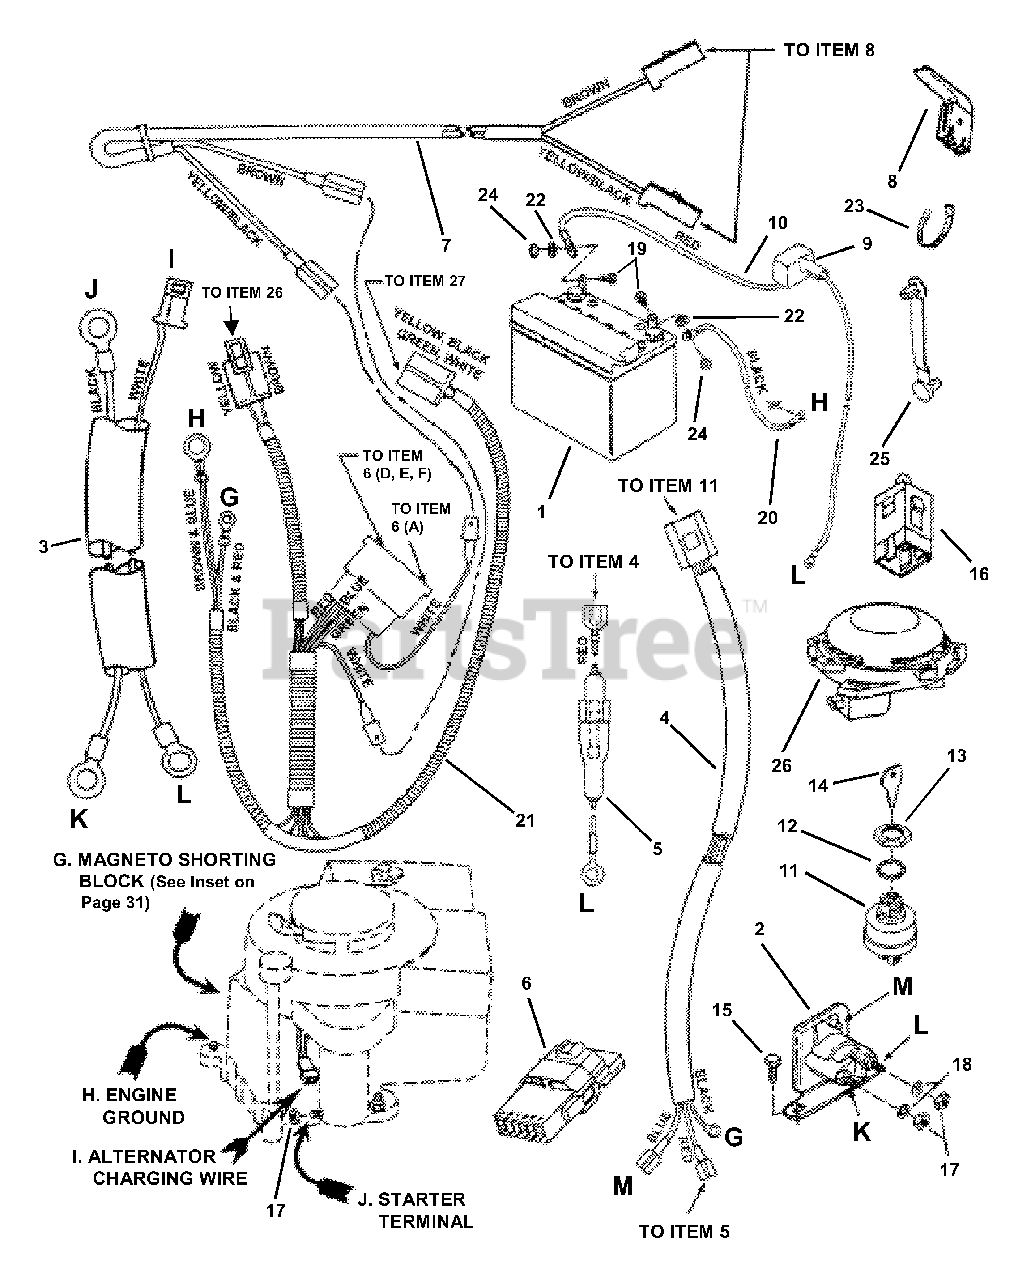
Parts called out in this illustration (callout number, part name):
1	KIT, 12Volt Dry Charge Battery
2	SOLENOID
3	HARNESS, Starter Wiring (Briggs Engines)
4	HARNESS, Ignition Wiring (Briggs Engines)
5	HOLDER, Fuse
6	INTERLOCK Module (Briggs)
7	HARNESS (Deck Interlock Wiring)
8	SWITCH, Deck Interlock (NO)
9	COVER, Battery Cable
10	CABLE, Positive (17" Long, Red)
11	SWITCH, Ignition
12	WASHER, 5/8 Internal Tooth Lock
13	NUT, 5/8-32 Hex
14	KEY, Switch
15	SCREW, 1/4-20 x 1/2" Hex Washer Self-Tap
16	SWITCH, Operator Presence Control (OPC) Traction (NC/NO)
17	NUT, 1/4-20 Hex, Grade 5 or B
18	WASHER, 1/4 Internal Tooth Lock
19	SCREW, 1/4-20 x 5/8" Hex Head Cap, Grade 5
20	CABLE, Negative (15" Long)
21	HARNESS, Operator Presence Control (OPC) Wire
22	RETAINER, 1/4" Bolt
23	TIE, 7" Long Cable
24	NUT, 1/4-20 Hex Center Lock
25	TIE, 2" Long Cable
26	SWITCH, Seat (8, 10, & 13 HP Engines) (NC)
